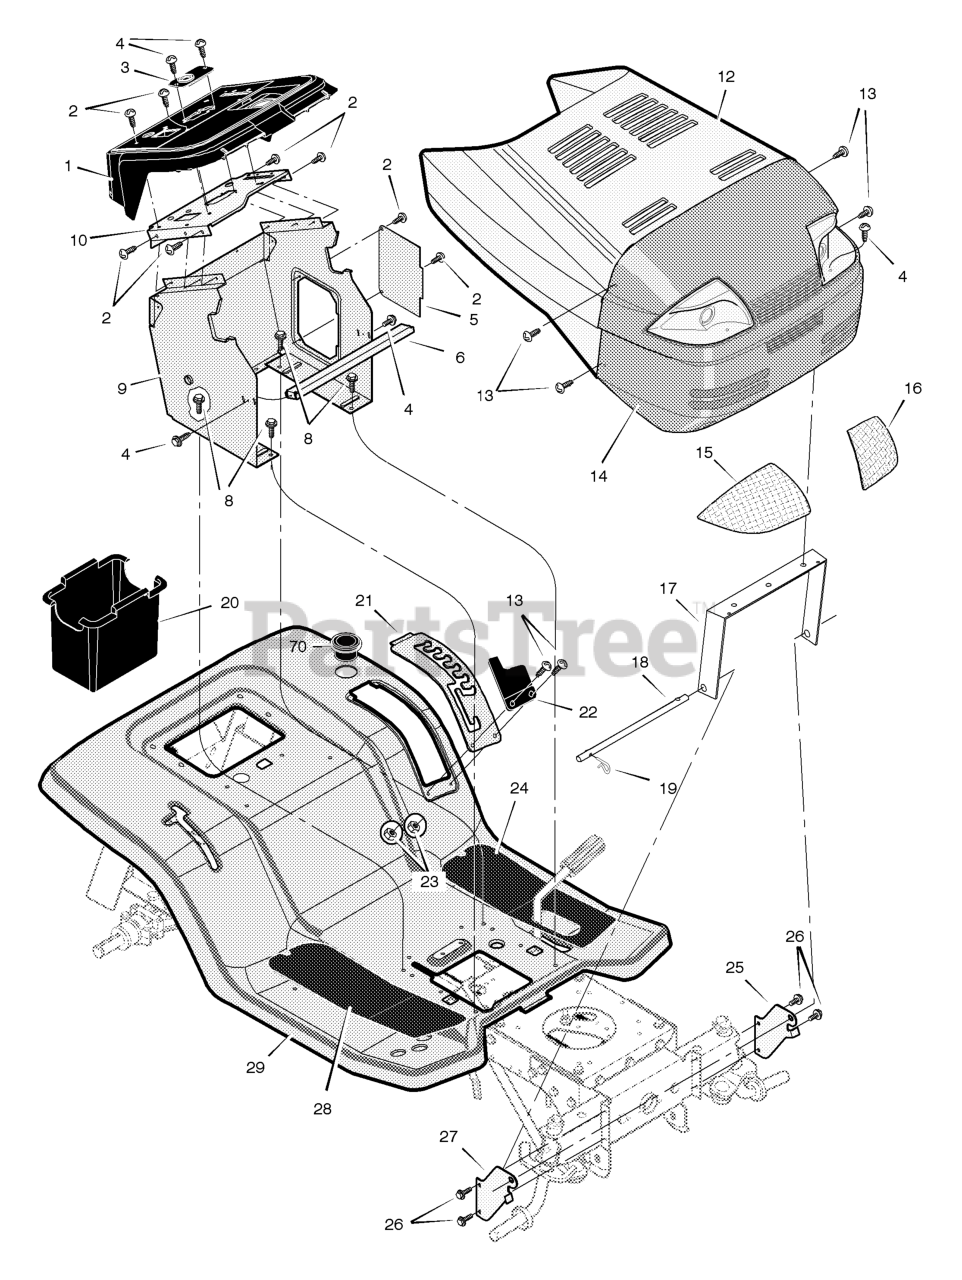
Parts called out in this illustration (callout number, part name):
2	Screw
3	Bearing, Upper Steering
5	Panel, Side Access
6	Channel, Support
9	Support, Dash
10	Plate, Dash
13	Bolt, Shoulder
14	Grille and Brace
15	Lens, Right
16	Lens, Left
17	Brace, Grille
18	Rod, Pivot
19	Pin, Hair
20	Container, Battery
21	Plate, Lift Detent
24	Mat, Left
25	Support, Left Grille
27	Support, Right Grille
28	Mat, Right
29	Deck, Seat
70	Holder, Beverage
